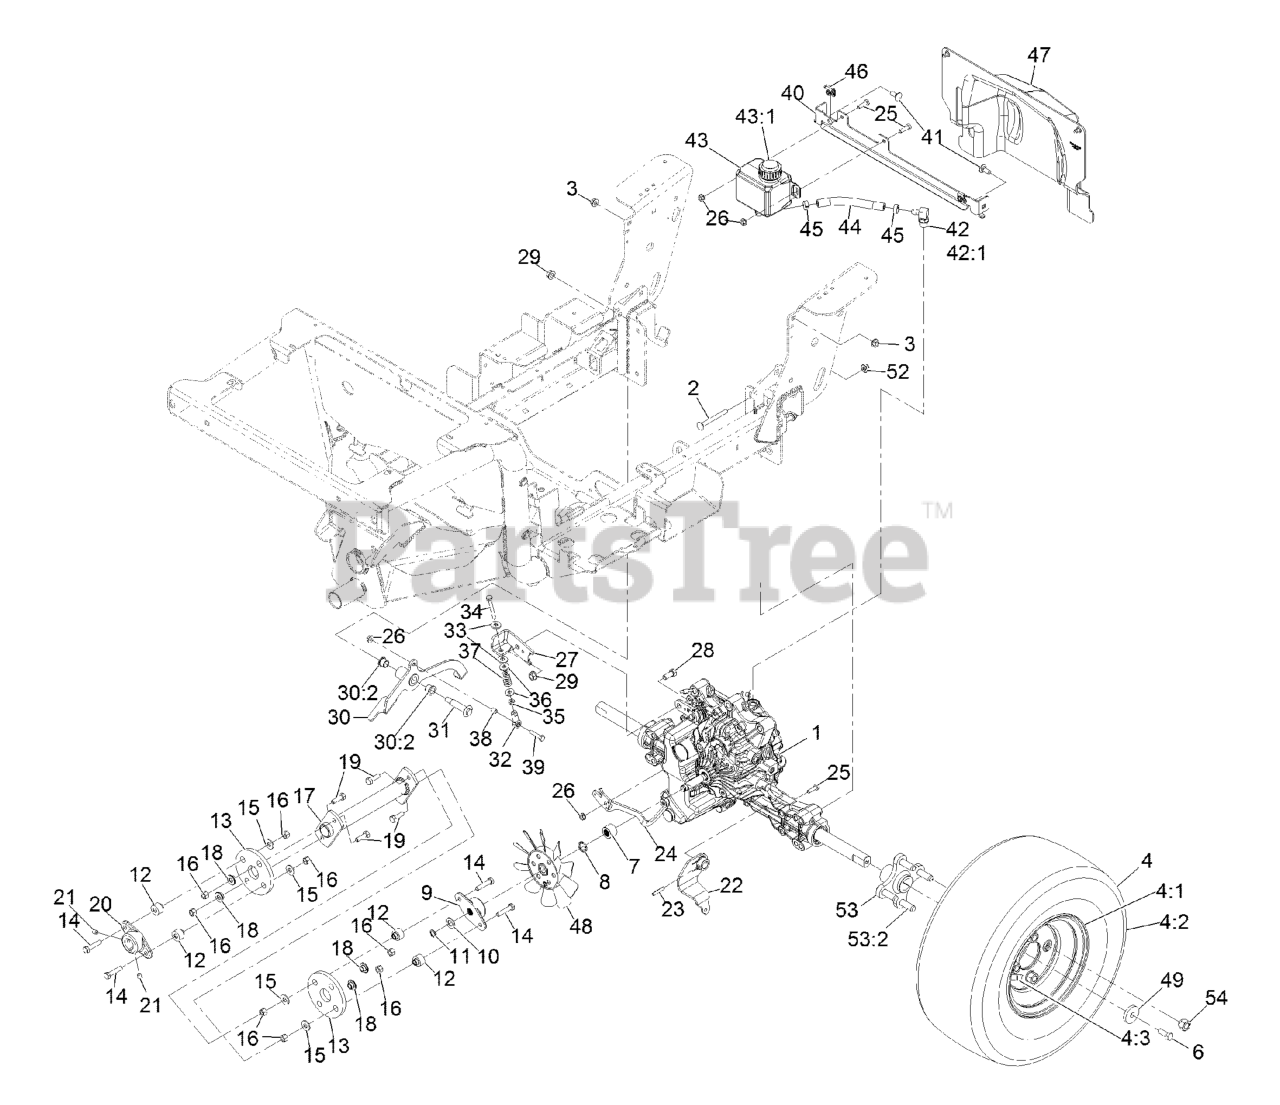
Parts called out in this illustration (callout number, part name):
1	TRANSAXLE
2	SCREW-CARR
4	Wheel And Tire ASM(18X7.5-8)
4:1	TIRE-4 PLY
4:2	Wheel, 8 X 5.375
4:3	Stem-Valve
6	SCREW-HH
7	SPACER-SHAFT, INPUT
8	WASHER-SPRING
9	HUB-SHAFT, TRANSAXLE
10	SPACER
11	RING-RETAINING
12	SPACER-COUPLING, RUBBER
13	COUPLING-RUBBER
14	SCREW-HH
15	WASHER-FLAT
16	NUT-HEX
17	Drive Shaft ASM, Welded
18	SPACER-COUPLER, RUBBER
19	SCREW-HH
20	HUB-SHAFT, ENGINE
21	SETSCREW
22	ARM-MOTION
23	PIN-SPIRAL
24	ARM-RELEASE
25	SCREW-HH
27	ARM-BRAKE
28	SCREW-HH
30	BRAKE LEVER ASM
30:2	BEARING-FLANGE
31	BOLT-SHOULDER
32	ROD END-BALL JOINT
33	WASHER-SPRING
34	SCREW-HH
35	NUT-JAM
36	WASHER-FLAT
37	SPRING-COMPRESSION
38	SPACER
39	SCREW-HH
40	BRACKET-MOUNT, TANK
41	SCREW-CARR
42	FITTING-90 DEG
42:1	O-RING
43	TANK ASM
43:1	CAP-TANK
44	HOSE-EXPANSION
46	RECEPTACLE-CLIP, MINI
47	TRANSAXLE COVER ASM
48	FAN-7 INCH
49	WASHER-CLUTCH
52	NUT-HF, NI
53	WHEEL HUB ASM
53:2	STUD-TYPE, DRIVE
54	NUT-LUG
